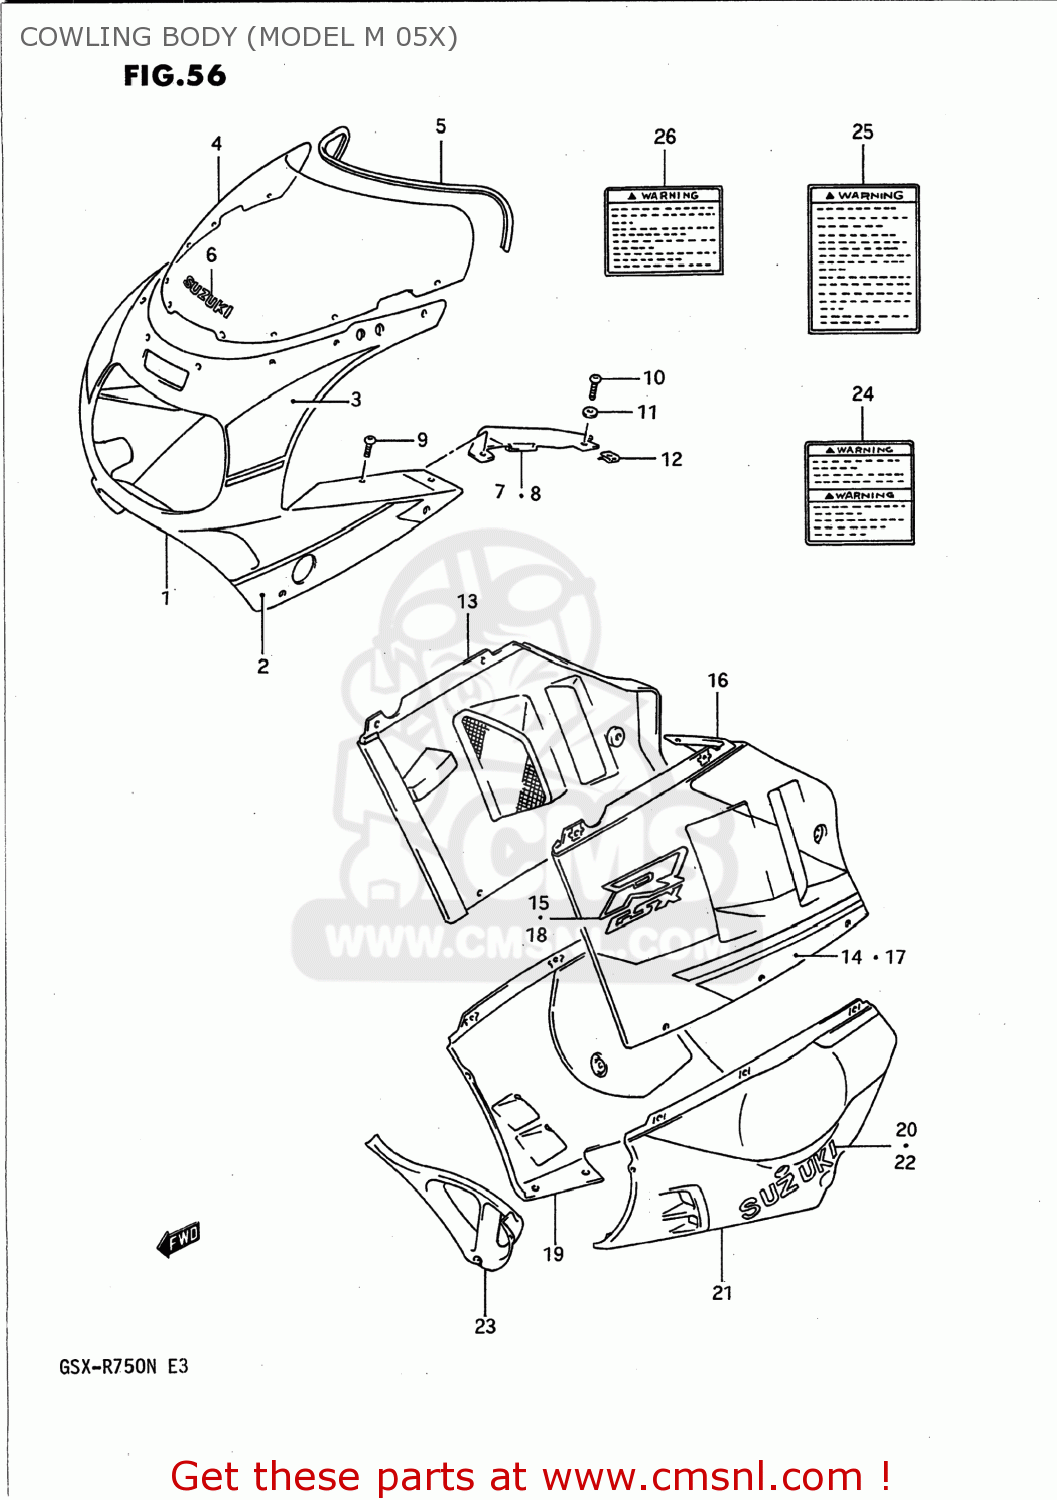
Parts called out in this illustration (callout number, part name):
1	BODY ASSEMBLY,COWLING
2	TAPE SET,COWLING
3	TAPE SET,COWL UPR FR
4	SCREEN SET,WIND
5	MOLDING,WINDSCREEN
6	EMBLEM,SUZUKI(WHITE)
7	PANEL,COWLING UPR,R
8	PANEL,COWLING,UPPER,LEFT
9	SCREW(5X10)
10	SCREW(5X14)
11	WASHER(5.2X11X1)
12	NUT
13	COVER,COWLING SIDE,RIGHT
14	TAPE,COWLING
15	EMBLEM,COWLING SIDE
16	COVER,COWLING SIDE,LEFT
17	TAPE,COWLING
18	EMBLEM,COWLING SIDE
19	COWLING COMP,UNDER,RIGHT
20	EMBLEM,COWLING,UNDER,RIGHT
21	COWLING COMP,UNDER,LEFT
22	EMBLEM
23	COWLING,UNDER,CENTER (B
24	LABEL (WARNING)
25	LABEL (WARNING SCREEN)
26	LABEL
